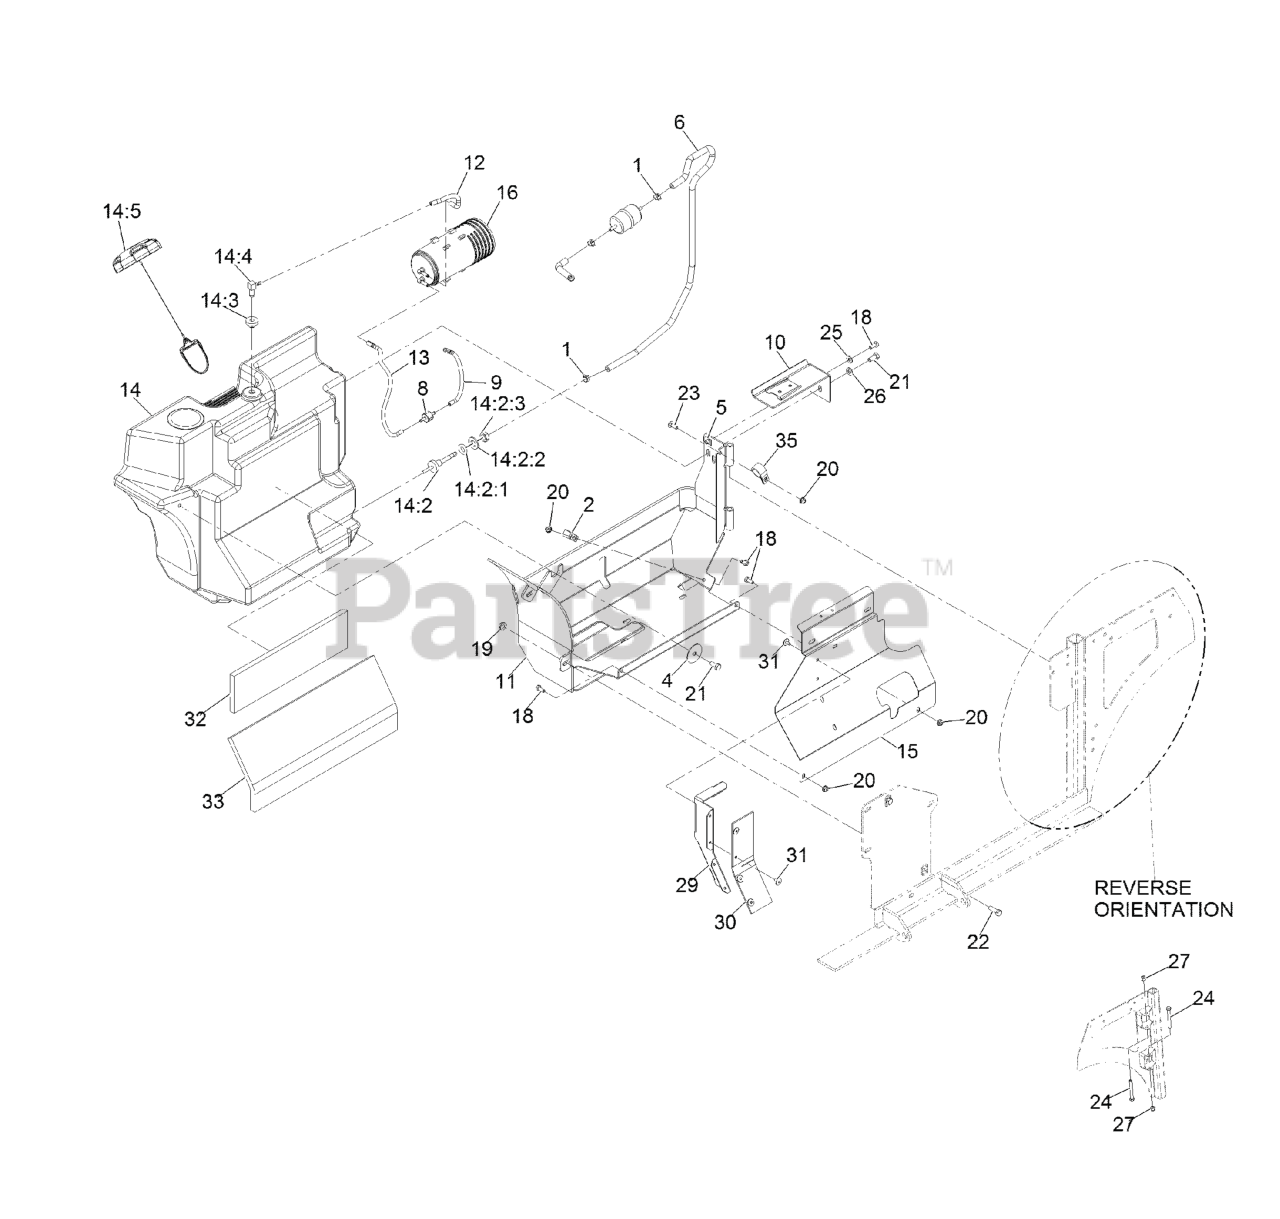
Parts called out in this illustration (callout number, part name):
1	CLAMP-HOSE
2	CLIP-LOOM
6	FUEL LINE ASM
8	VALVE-CHECK, VACUUM
9	HOSE-VENT, FORMED
10	CANISTER BRACKET ASM
11	TANK FRAME ASM
12	HOSE-VENT, FORMED
13	HOSE-VENT, FORMED
14	FUEL TANK ASM
14:2	FITTING-FUEL, BULKHEAD
14:2:1	O-RING,BULKHEAD FITTING
14:2:2	WASHER-FLAT
14:2:3	NUT-JAM
14:3	BUSHING
14:5	CAP-FUEL, RATCHETING
15	PANEL-TANK SHIELD
16	CANISTER-CARBON, 800CC
18	SCREW-HH
21	SCREW-HH
22	SCREW-HH
23	BOLT-CARR
24	SCREW-HH
25	WASHER-FLAT
26	WASHER-PLAIN
27	NUT-LOCK, NI
29	DEFLECTOR-AIR
30	FLAP-RUBBER
31	RIVET-POP
32	INSULATION-FOAM PAD, FRON
33	INSULATION-FOAM PAD, REAR
35	R-CLAMP
